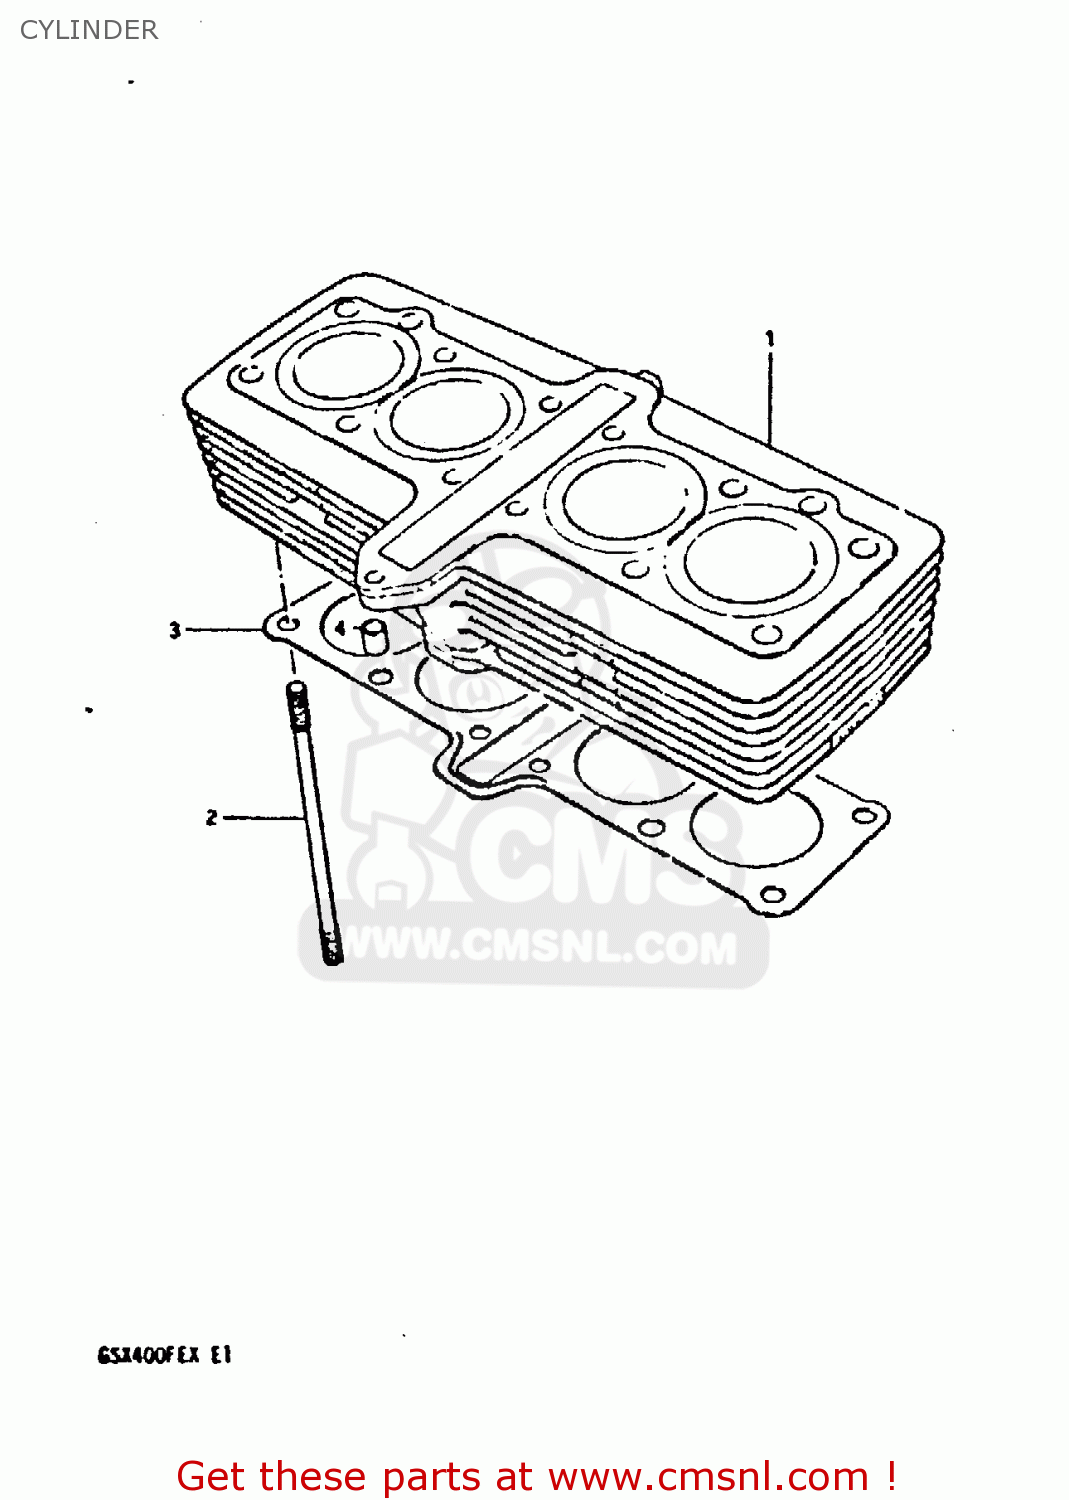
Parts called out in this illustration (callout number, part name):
1	CYLINDER
2	STUD
3	GASKET (MCA)
4	PIN
